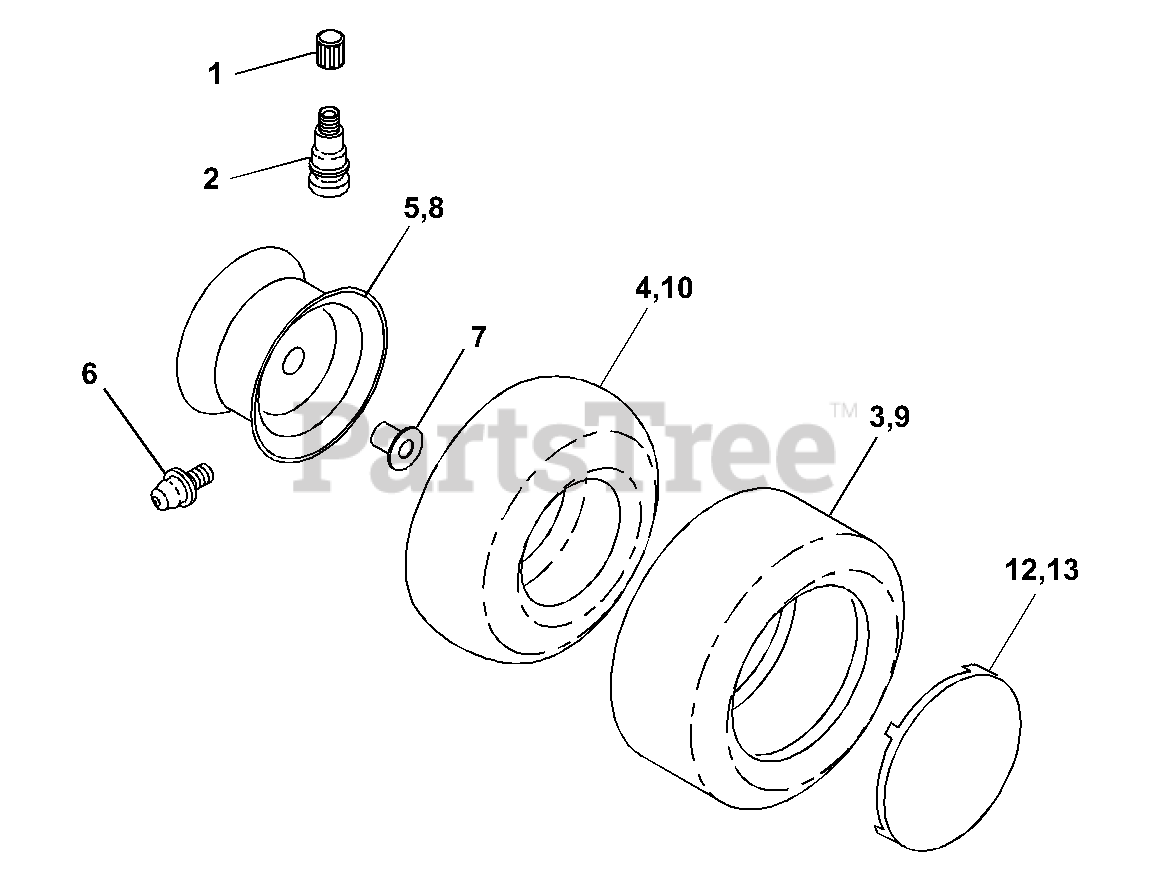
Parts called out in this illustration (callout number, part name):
1	Cap Valve Tire
2	Stem Valve
3	Tire F Ts 15 X 6 0 - 6 Service
4	Tube Front (Service Item Only)
5	Rim Asm 6" front White Service
6	Fitting Grease (Front Wheel Only)
7	Bearing Flange (Front Wheel Only)
8	Rim Asm 8" rear White Service
9	Tire R Ts 20 10 C Service
10	Tube Rear (Service Item Only)
12	Cover Wheel 6" white
13	Cover Wheel 8" white
